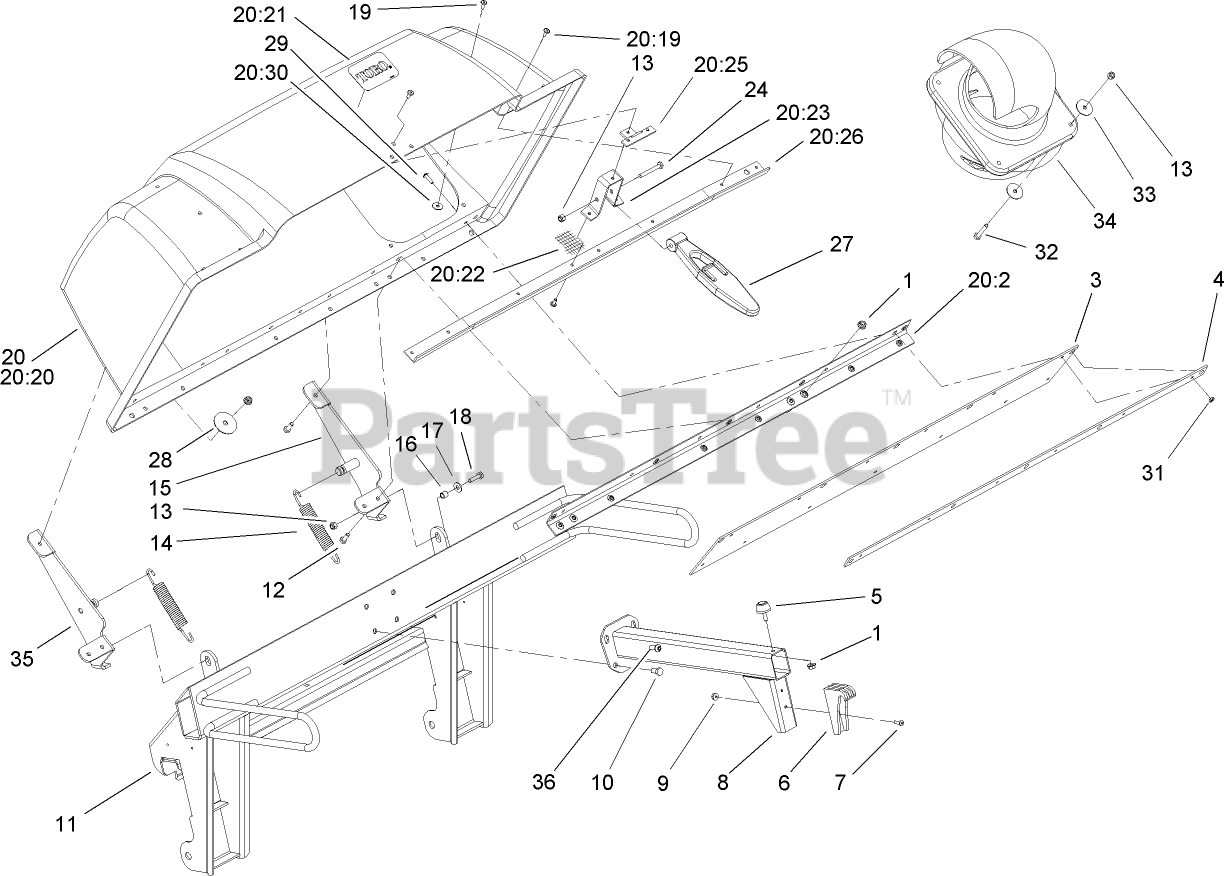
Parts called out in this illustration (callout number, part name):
1	NUT-HF
3	SEAL-HOOD
4	PLATE-BACKING
5	BUMPER
7	SCREW-PPH
8	SUPPORT-BAG
9	NUT-HF
10	SCREW-HH
11	UPRIGHT-BAGGER
12	SCREW-HH
13	NUT-LOCK, NI
14	Spring-Extension
15	HINGE-RH
16	SPACER
17	WASHER-FLAT
18	SCREW-HH
19	RIVET-BLIND
20	HOOD ASM
20:2	STIFFENER-BAGGER, TOP
20:19	RIVET-BLIND
20:20	TOP-BAGGER
20:22	SCREEN-BAGGER
20:23	ANCHOR-LATCH
20:25	REINFORCEMENT-LATCH
20:26	SUPPORT-SCREEN
20:30	WASHER-FLAT
24	SCREW-HH
28	WASHER
29	SCREW-HEAD, TRUSS
31	NUT-LOCK, SIDE
32	SCREW-HH
33	WASHER-FLAT
34	ADAPTER-TUBE, UPPER
35	HINGE-LH
36	SCREW-HSBH
